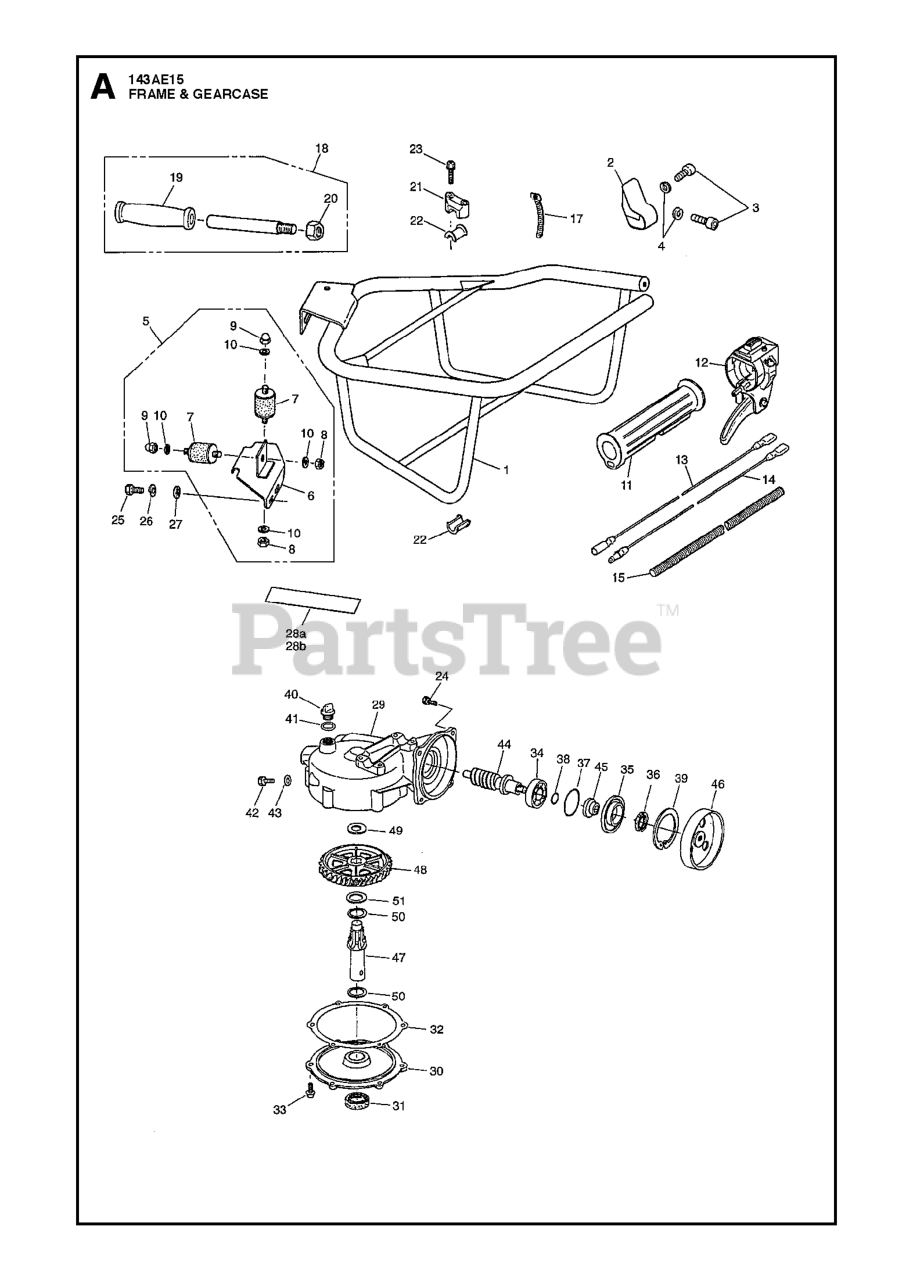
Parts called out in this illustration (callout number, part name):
2	BRACKET, FRAME
12	LEVER (FLEX. LEVER)(RPLS -13)
18	HANDLE COMP
39	RING, SNAP, M62 x 2.0
48	WHEEL GEAR
